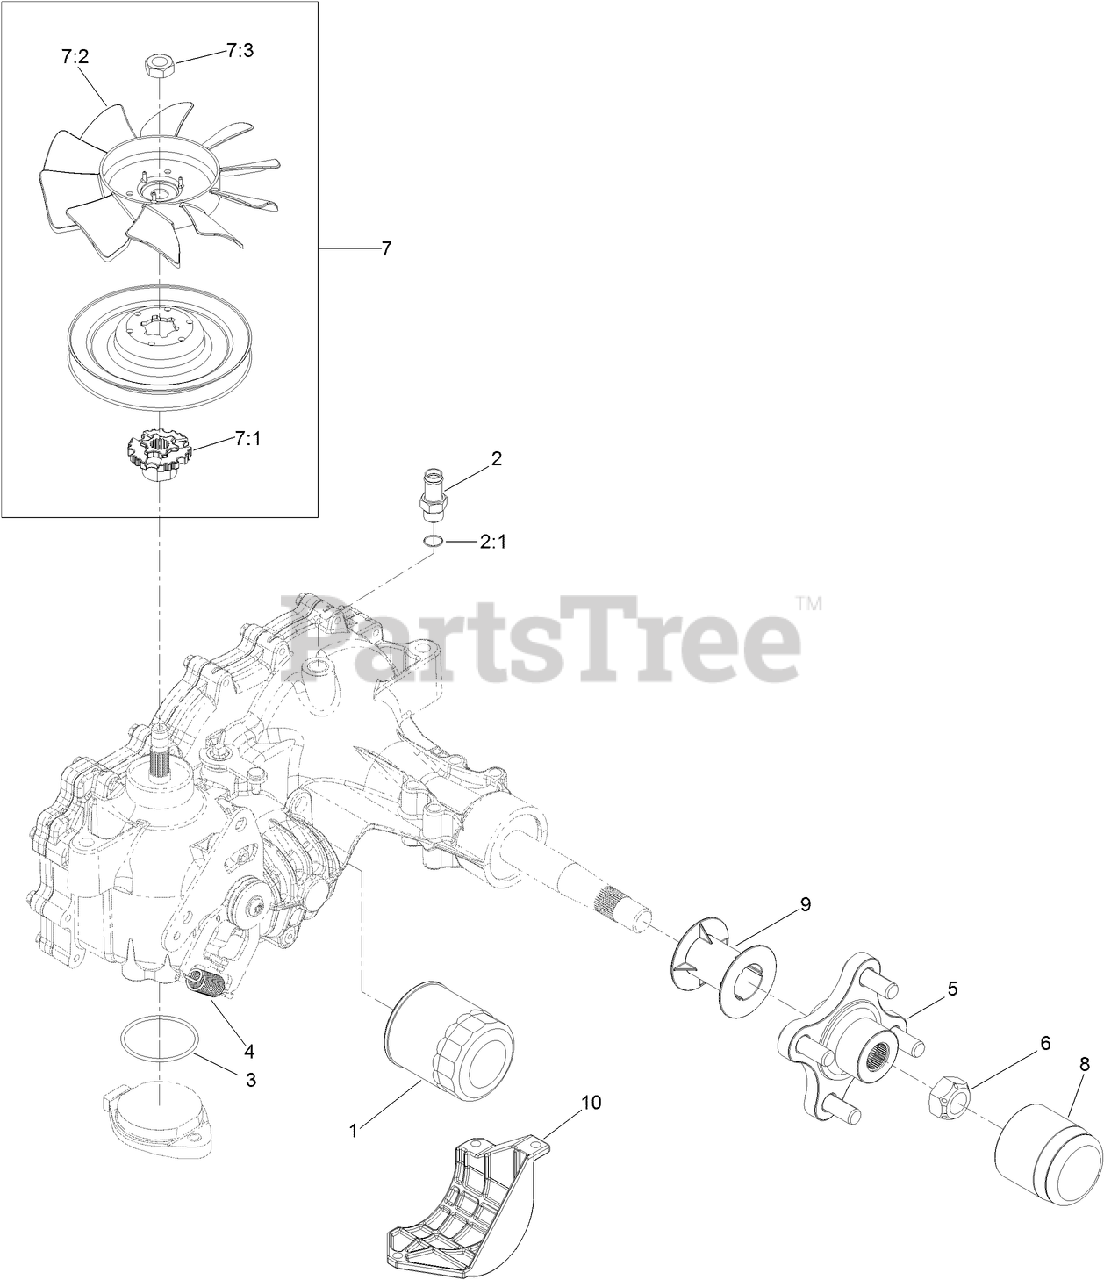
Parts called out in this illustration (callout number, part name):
1	ELEMENT-OIL FILTER, HYD
2	ADAPTER-STRAIGHT
2:1	O-RING
3	O RING-SEAL
4	SPRING-EXTENSION
5	HUB-OFFSET
6	NUT-HUB
7	FAN AND PULLEY KIT
7:1	HUB-FAN
7:3	NUT-HJ
8	CAP-AXLE, LONG
9	TUBE-AXLE
10	GUARD-FILTER, LH
